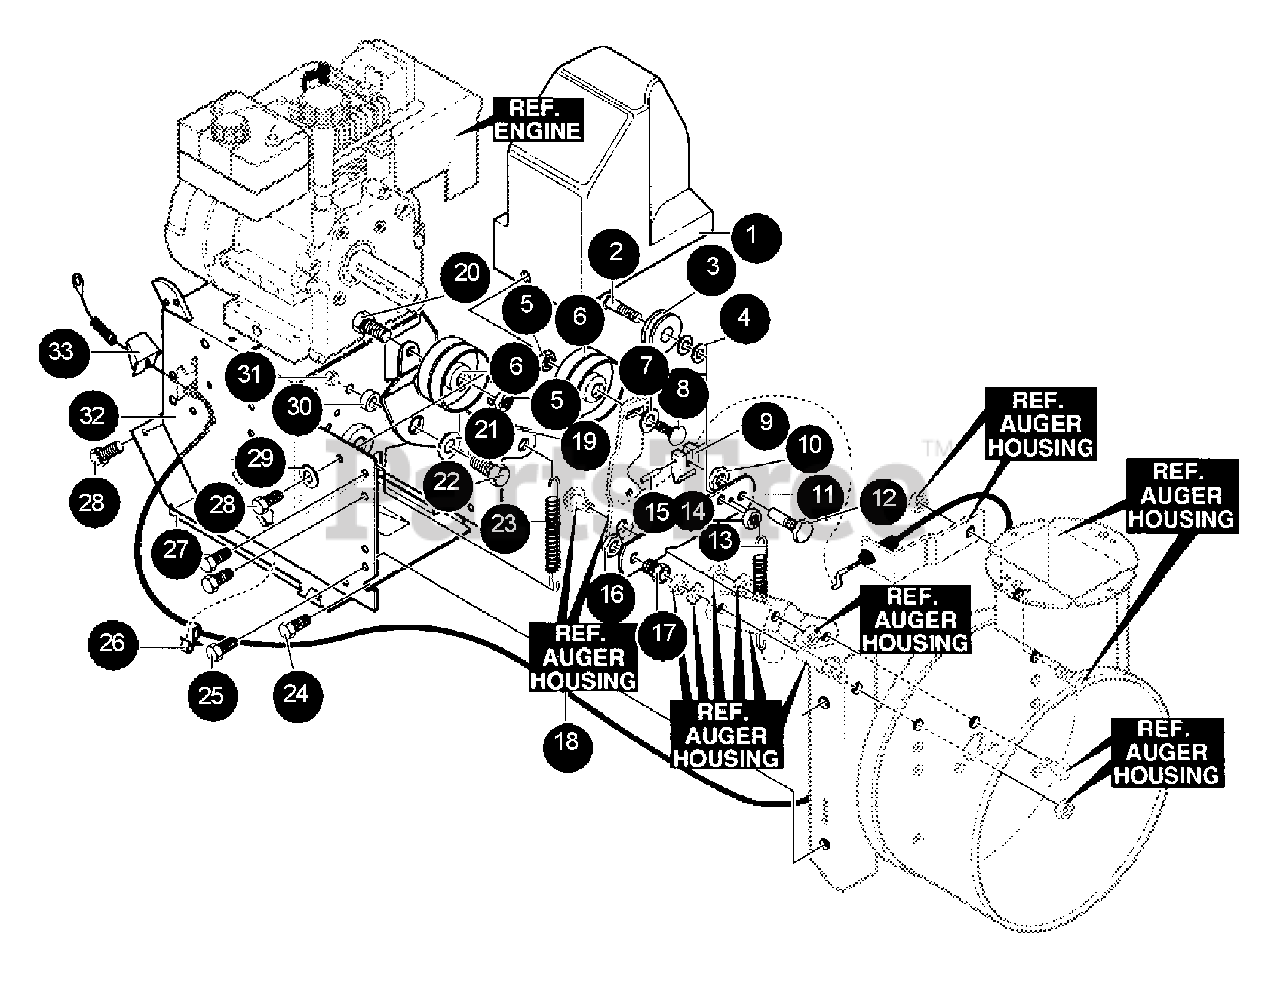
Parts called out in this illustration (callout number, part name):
1	BELT COVER KIT
2	BOLT - .375X.375 HHSH 1/4-20
3	PULLEY
4	WASHER
5	LOCKNUT - 3/8-16
6	PULLEY, IDLER
7	WASHER - .506 X .75X .024"
8	BOLT, 3/8-16X1.25 CARR
9	PAD, AUGER/IMPELLER BRAKE
10	LOCKNUT - 1/2-20
11	BRACKET
12	BOLT, BRAKE ARM
13	SPRING, IDLER BRAKE
14	NUT - 1/4-20
15	PIN - SPRING
16	NUT - 9/16-18
17	BOLT, BRAKE ARM 9/16-18
18	CABLE, AUGER
19	LEVER, IDLER ARM TRACTION
20	SCREW - 3/8-16 X 1-1/4"
21	WASHER - .328X1.25X.075
22	SCREW - 5/16-18 X 3/4"
23	SPRING, IDLER
24	SCREW - 1/4-20 X .63" -- TAPPING
25	SCREW - 5/16-18 X 1/2"
26	CLIP, CABLE
27	COVER, BOTTOM
28	SCREW - 1/4-20 X .63" -- TAPPING
29	WASHER
30	BUSHING, IDLER LEVER
31	NUT - 5/16-18
32	FRAME ASSY
33	SHIELD, CABLE GUARD
